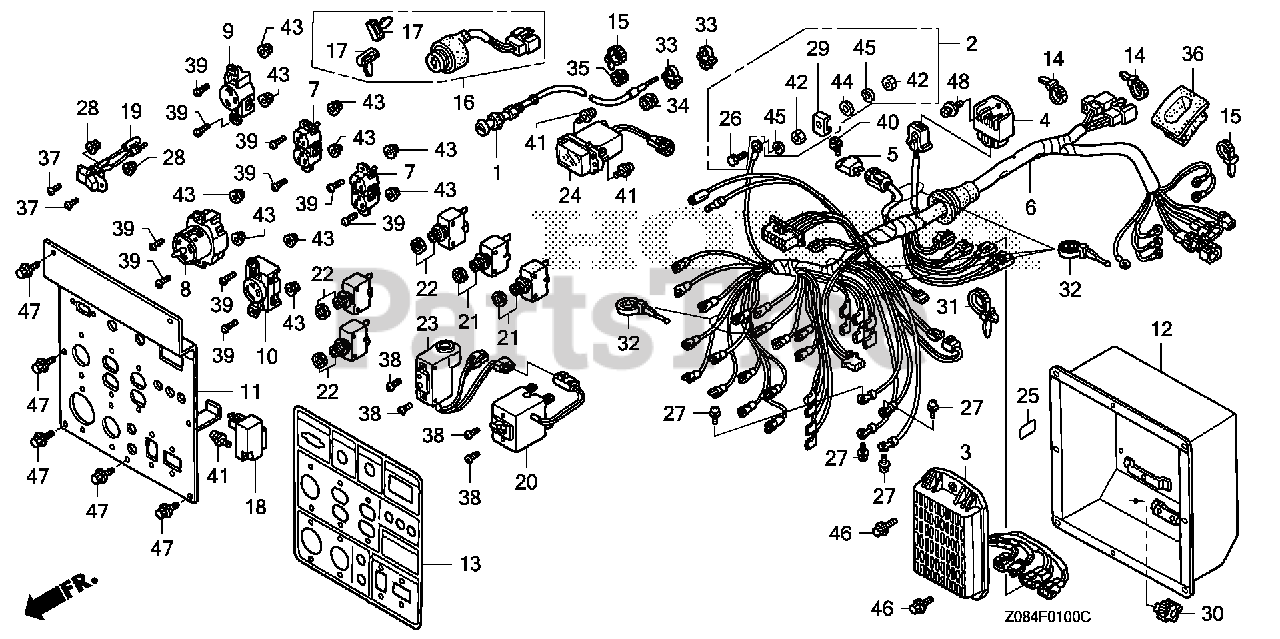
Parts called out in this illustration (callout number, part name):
1	CABLE, CHOKE
2	TERMINAL SET, GROUND
3	A.V.R. ASSY.
4	RECTIFIER ASSY.
5	DIODE, D.C.
6	WIRE HARNESS ASSY., CONTROL
7	RECEPTACLE (20A/125V) (MATSUSHITA)
8	RECEPTACLE (50A/125-250V)
9	RECEPTACLE (30A/125V)
10	RECEPTACLE (30A/125-250V)
11	PANEL, CONTROL *NH105* (MAT BLACK)
12	COVER, CONTROL BOX *NH105* (MAT BLACK)
13	MARK, PANEL
14	TIE, CABLE
15	TIE, CABLE (C)
16	SWITCH ASSY., COMBINATION
17	KEY (HONDALOCK)
18	THROTTLE UNIT, AUTO (SAWAFUJI)
19	SWITCH, AUTO THROTTLE
20	BREAKER, CIRCUIT (41A)
21	PROTECTOR, CIRCUIT (20A)
22	PROTECTOR, CIRCUIT (30A)
23	RELAY ASSY. (GFCI)
24	METER ASSY., HOUR
25	MARK, GRAND
26	BOLT, HEX. (6X28)
27	SCREW-WASHER (6X12)
28	NUT, FLANGE (3MM)
29	RETAINER (6MM)
30	CLIP, CORD
31	TIE, CABLE (NATURAL 225X5.0)
32	TIE, CABLE (NATURAL 154X3.4)
33	CLIP, CORD
34	RUBBER, CONTROL BOX
35	GROMMET, CHOKE CABLE
36	GROMMET, CONTROL WIRE HARNESS
37	SCREW, PAN (3X6)
38	SCREW, PAN (4X6)
39	SCREW, PAN (4X12)
40	SCREW-WASHER (5X12)
41	SCREW-WASHER (5X16)
42	NUT, HEX. (6MM)
43	NUT, FLANGE (4MM)
44	WASHER, PLAIN (6MM)
45	WASHER, SPRING (6MM)
46	BOLT, FLANGE (8X16)
47	BOLT, FLANGE (6X12)
48	BOLT-WASHER (6X15)
